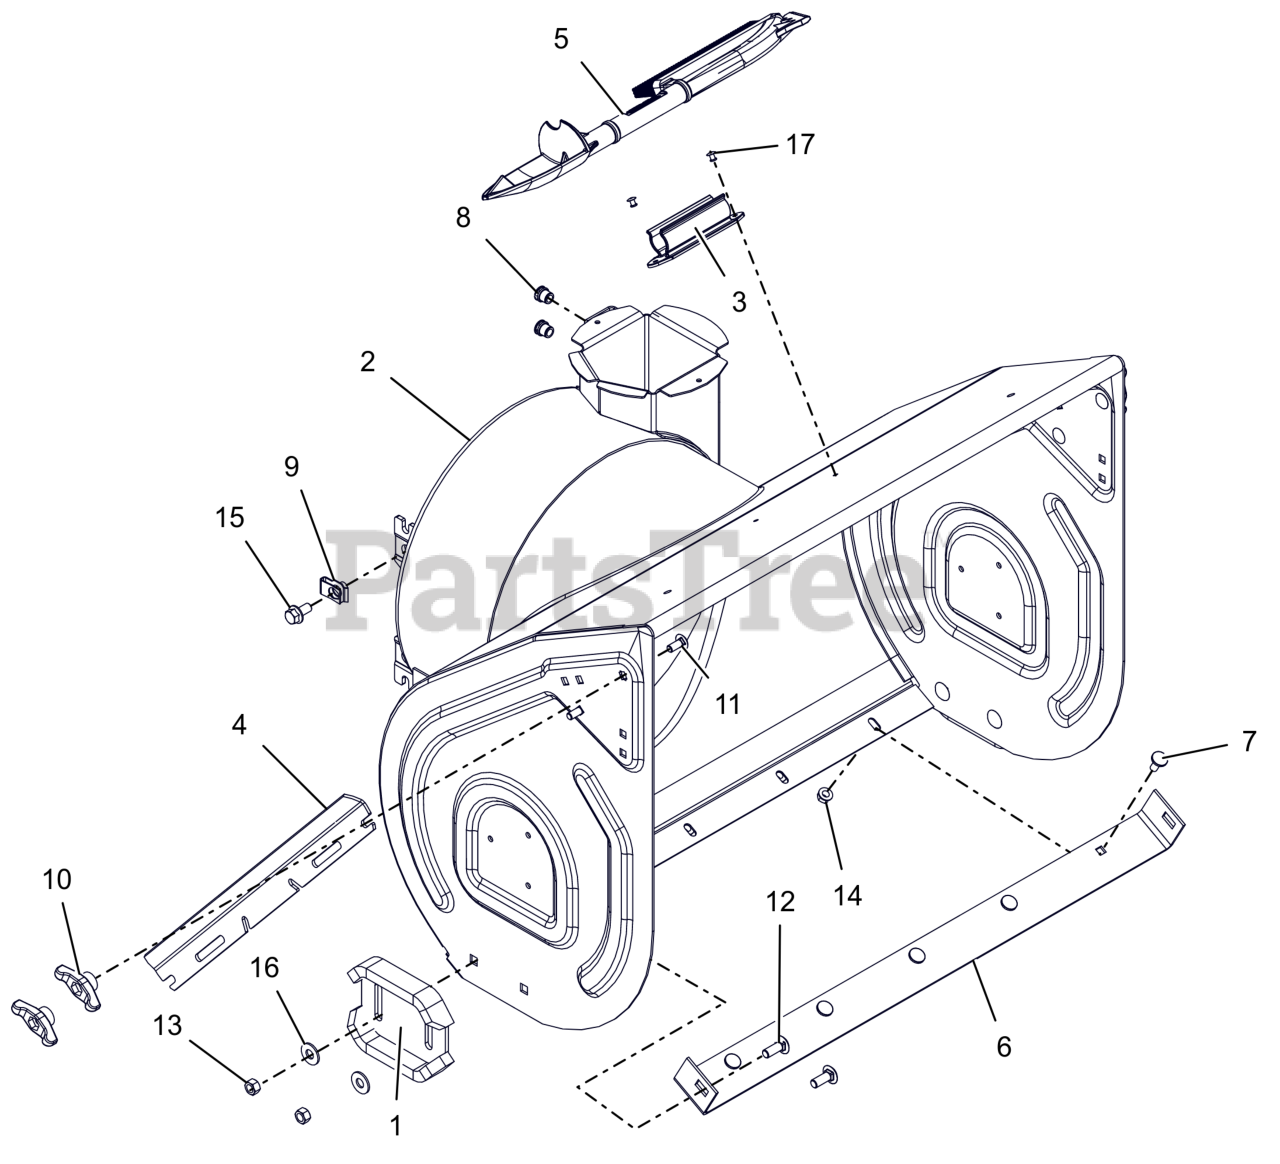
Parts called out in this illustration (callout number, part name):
1	RUNNER, SKID SHOE
2	BLOWER HOUSING W/DECAL 28"
3	MOUNT, SNOW CLEAN OUT
4	CUTTER, DRIFT
5	DEVICE, SNOW CLEAN OUT W/BRUSH
6	BLADE, SCRAPER-28"
7	BOLT, MODIFIED HEAD CARRIAGE
8	NUT,THD,INSERT .38-16 ZC120
9	NUT-RTNR .375-16X.37
10	KNOB,WING .31-18 UNC NYL/TALC
11	BLT, RHSSN.31-18X.750 G5 ZCC
12	BLT,RHSSN .38-16X1.00 G5 ZCC
13	NUT-LK-CTR .38-16 ZC120
14	NUT-LK-TOP-FLG .312-18 GF ZCC
16	WSHR,FLT .438X1.00X.083 ZCC
17	RVT, POP .1875 ZCC
